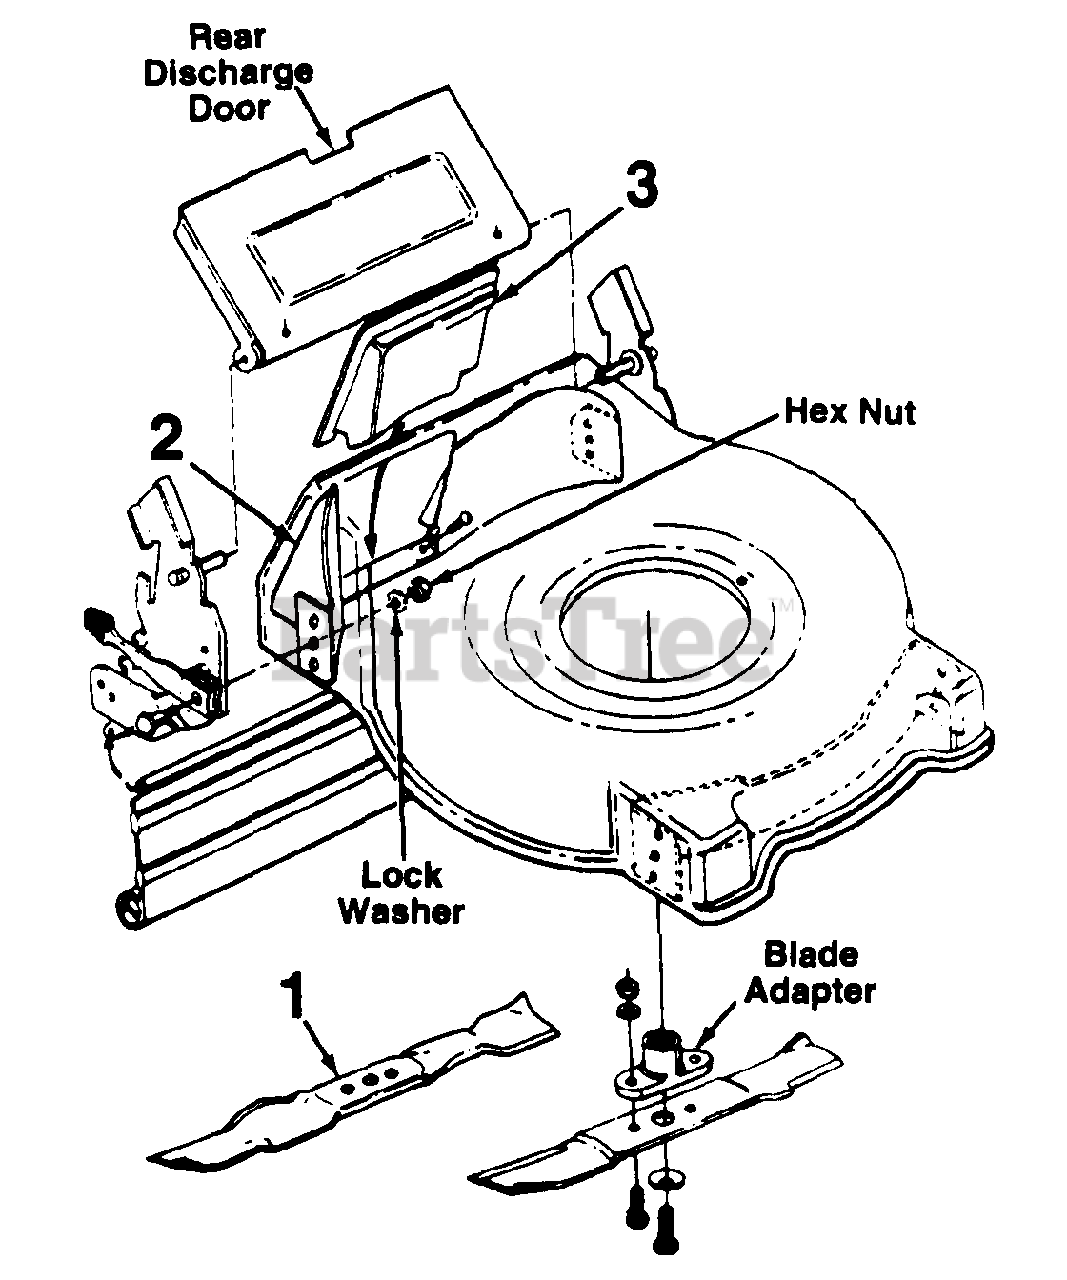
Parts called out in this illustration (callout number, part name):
1	21" Mulching Blade
1	19" Mulching Blade
2	Mulching Baffle - R.R.
3	Mulching Baffle Plug
